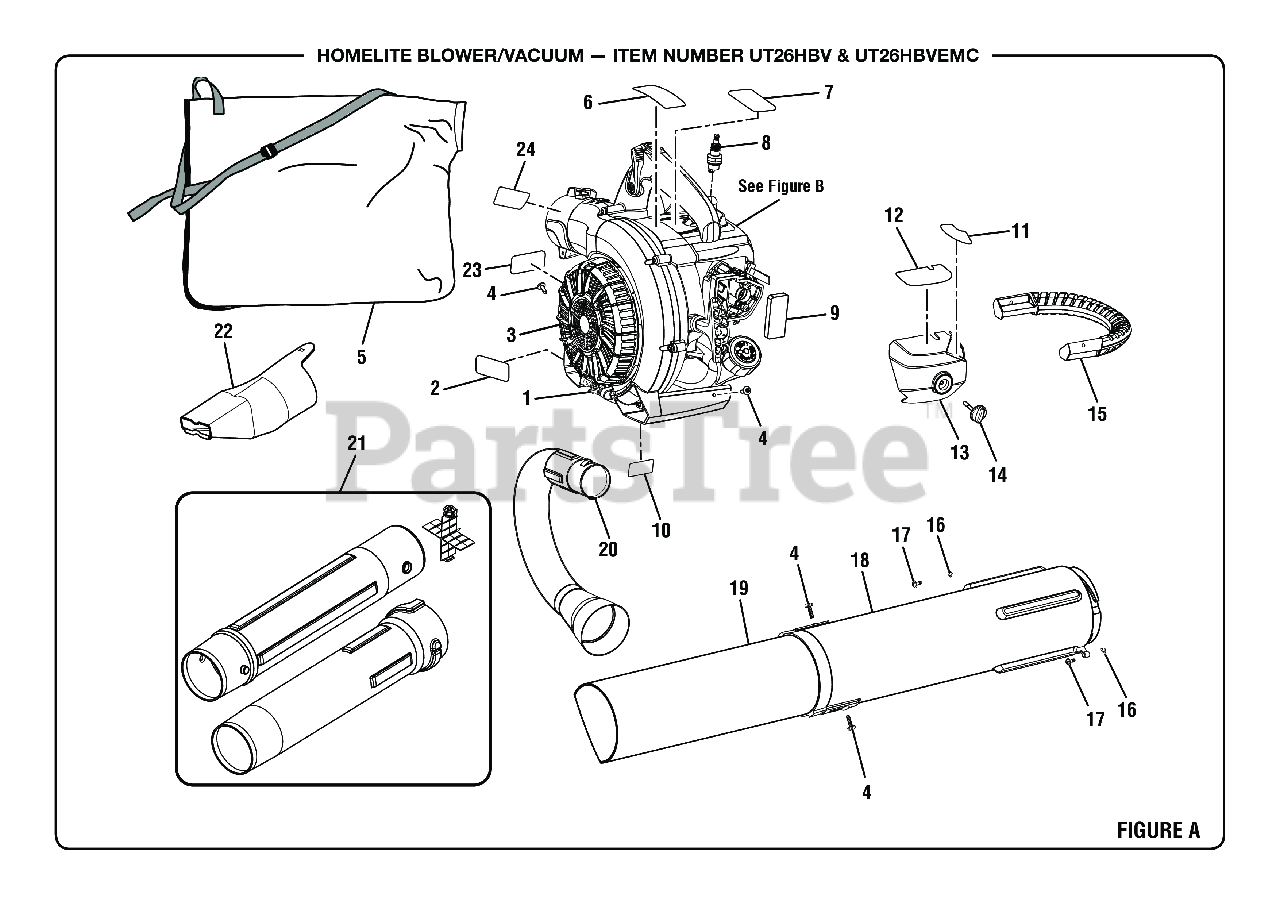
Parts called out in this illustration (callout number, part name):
1	Vacuum Door Spring
2	Warning Label (Combustion)
3	Vacuum Door
4	Vacuum Tube Screw (10-14 x 1/2 in., T25 Torx Truss Hd. T.F.)
5	Vacuum Bag w/Shoulder Strap
6	Warning Icon Label
7	Logo Label (Small)
8	Spark Plug (Champion RCJ6Y)
10	EMC ICES-2/NMB-2 Label (Canada)
11	Choke Label
12	Starting Label
13	Air Filter Cover
15	Vacuum Handle
16	E-ring (Retaining Ring)
17	Screw (1/4-20 x 3/4 in., Soc. Hd.)
18	Upper Vacuum Tube
19	Lower Vacuum Tube
20	Vacuum Bag Adaptor
21	Blower Tube Assembly
22	Wet Leaf Nozzle
23	Hot Surface Label
24	Tube Removal Label
